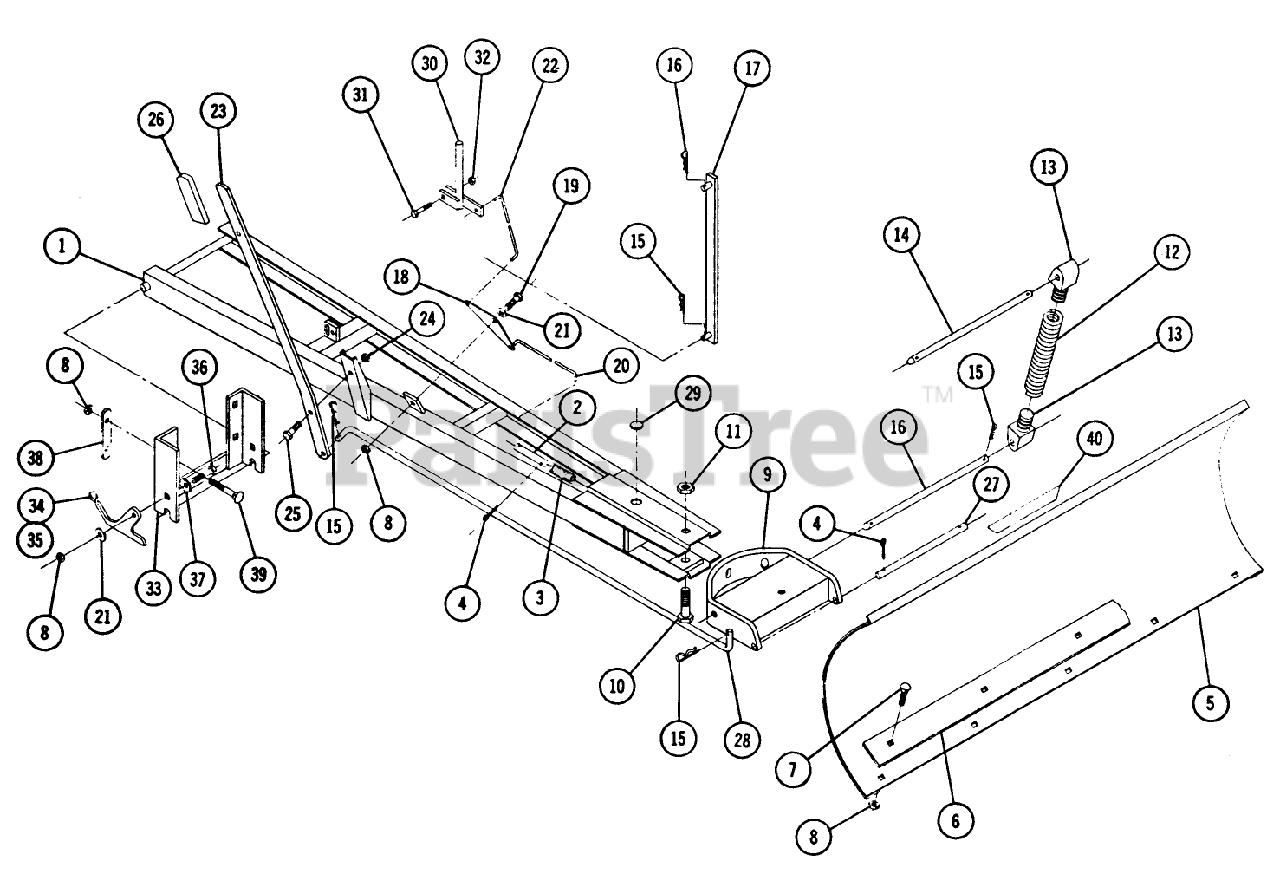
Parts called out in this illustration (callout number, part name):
3	SPRING-COMPRESSION
4	Cotter Pin
5	ORD 109593 & 109596
7	Bolt-3/8-16 x 3/4
8	3/8-16 E.S.
10	Bolt Hex 3/4-16 x 3 3/4
11	Nut-3/4-16 E.S.
14	ROD-PIVOT, BLADE
15	Hairpin
16	Hairpin
19	Bolt 3/8-16 x 1
20	LOWER INDEX ROD
21	Washer
22	Rod-Upper Index
23	Lever
24	Nut-1/2-13
25	Bolt Hex 1/2-13 x 1
26	GRIP
27	ROD-LOWER
29	PLUG
31	Bolt-Hex 1/4-20
32	Nut-Nylok
36	Bolt, 3/8-16 x 1/2
38	BRACKET-REAR LINK MOUNTING
39	Bolt-Carriage 3/8-16 x 3 1/4
